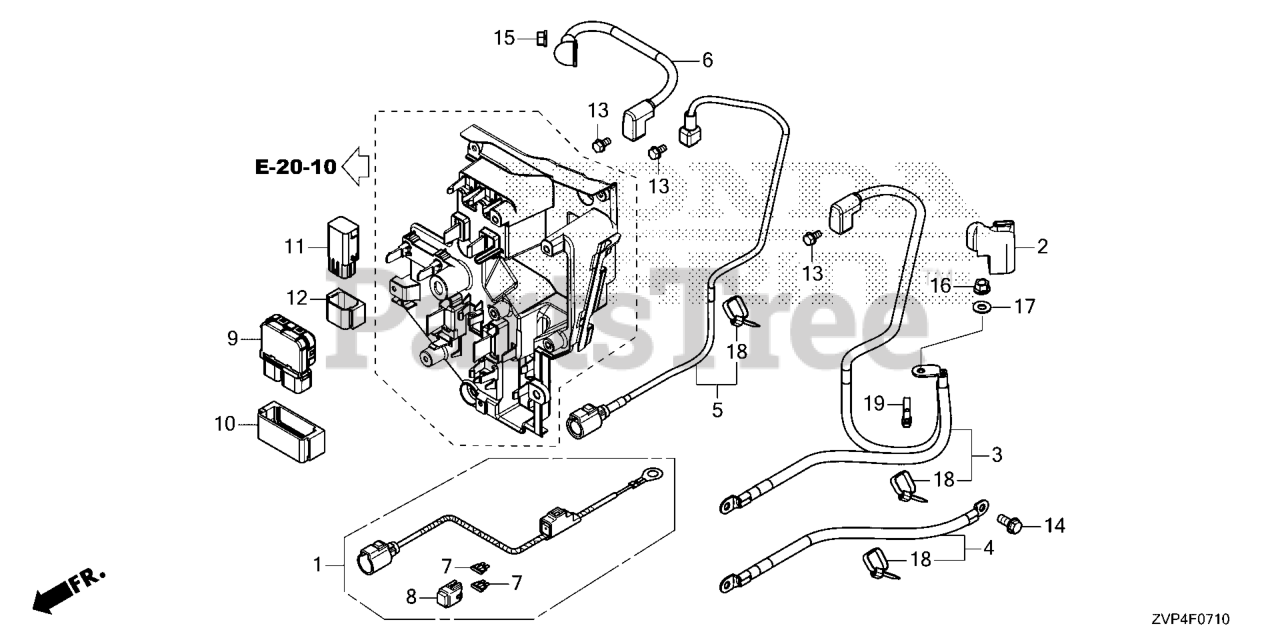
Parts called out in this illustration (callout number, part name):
1	HARNESS ASSY., POWER
2	COVER, BAT TERMINAL
3	WIRE, BATTERY PLUS
4	WIRE, BATTERY MINUS
5	WIRE, BATTERY SYSTEM
7	FUSE, BLADE (40A)
8	COVER ASSY., FUSE (40A)
9	RELAY, POWER TILT
10	SUSPENSION
11	RELAY ASSY., SENSING
12	CUSHION, RELAY
13	BOLT, FLANGE (6X12)
14	BOLT, FLANGE (8X18)
15	NUT-WASHER (8MM)
16	NUT-WASHER (8MM)
17	WASHER, PLAIN (8MM)
18	BAND, WIRE (165MM) (BLACK)
19	BAND, WIRE (BLACK)
